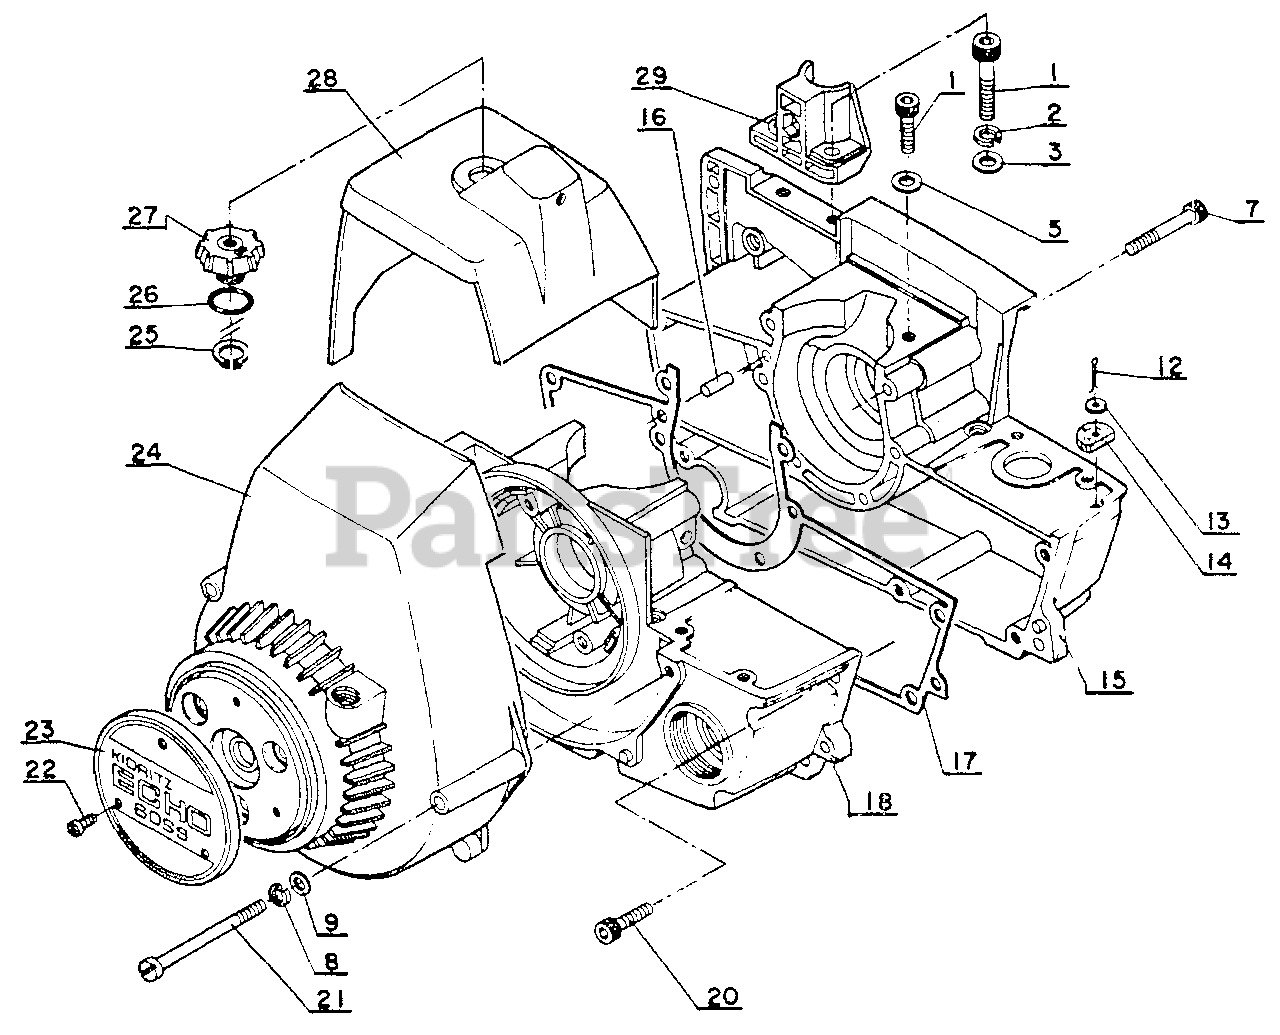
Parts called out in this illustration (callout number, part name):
1	BOLT 6×25
2	WASHER, SPRING 6
3	WASHER 6.5×11.5×0.8
7	BOLT M5×35
8	WASHER, SPRING 5
9	WASHER, FLAT 5.5×10×0.8
12	PIN, COTTER
13	WASHER 2 MM
14	PACKING
15	CRANKCASE KIT
16	PIN, LOCATING 5×10
17	GASKET, CRANKCASE
20	BOLT 5×20
22	SCREW 3×6
23	NAMEPLATE
24	CASE, STARTER
26	O-RING 14 MM
28	COVER, CYLINDER
29	BRACKET, HANDLE
